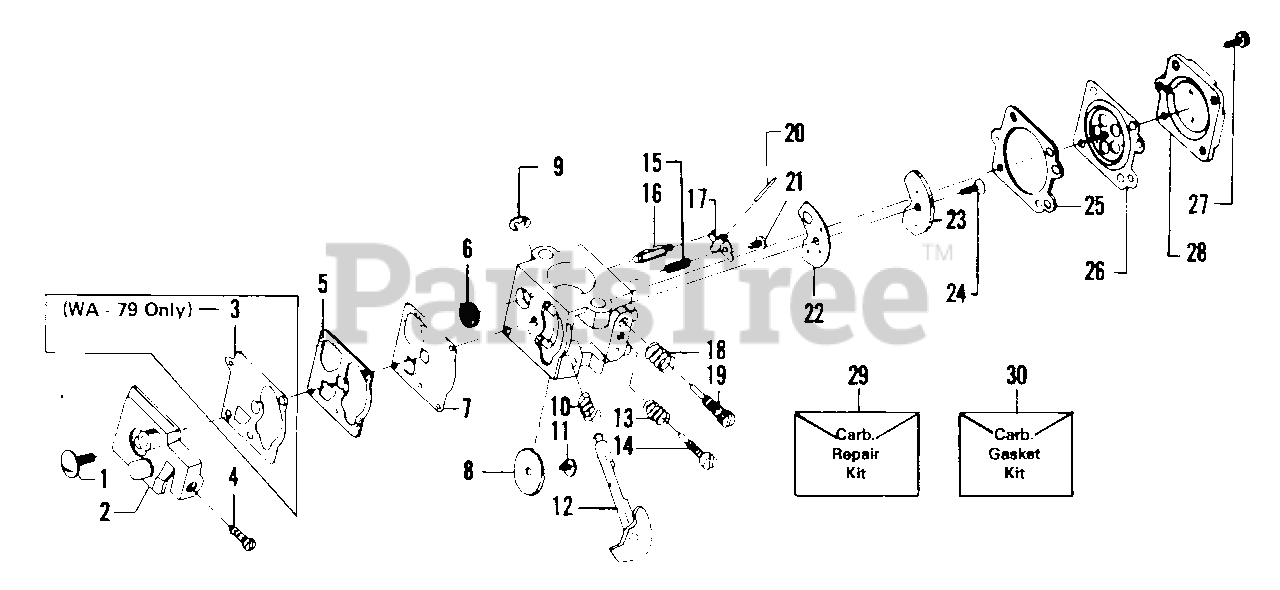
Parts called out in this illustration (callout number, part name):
1	Screw - Pump Cover
2	WA - 149 (#35183)
3	Diaphragm - Pump WA - 79 Only
4	Screw - Idle Adjustment
5	Gasket - Pump
5	WA - 149 (#35183)
6	Screen - Inlet
7	Diaphragm - Pump
7	WA - 149 (#35183)
8	Valve - Throttle
9	Clip - Throttle Shaft
10	Spring - Throttle Return
11	Screw - Throttle Valve
12	Shaft Assembly - Throttle
13	Spring - Idle Needle
14	Needle - Idle
15	Spring - Metering Lever
16	Valve - Inlet Needle
17	Lever - Metering
18	Spring - Hi Speed Needle
19	Needle - Hi Speed
20	Pin - Metering Lever
21	Screw - Metering Lever Pin
22	Gasket - Circuit Plate
23	Plate - Circuit
24	Screw - Circuit Plate
25	Gasket - Metering Diaphragm
26	Diaphragm Assembly - Metering
27	Screw - Assembly - Metering Cover & Throttle Shaft Clip
28	Cover - Metering Diaphragm
29	Kit Carb - Kwik Repair
29	WA - 149 (35183)
30	Kit Carb.- Gasket/Diaphragm
30	WA - 149 (#35183)
